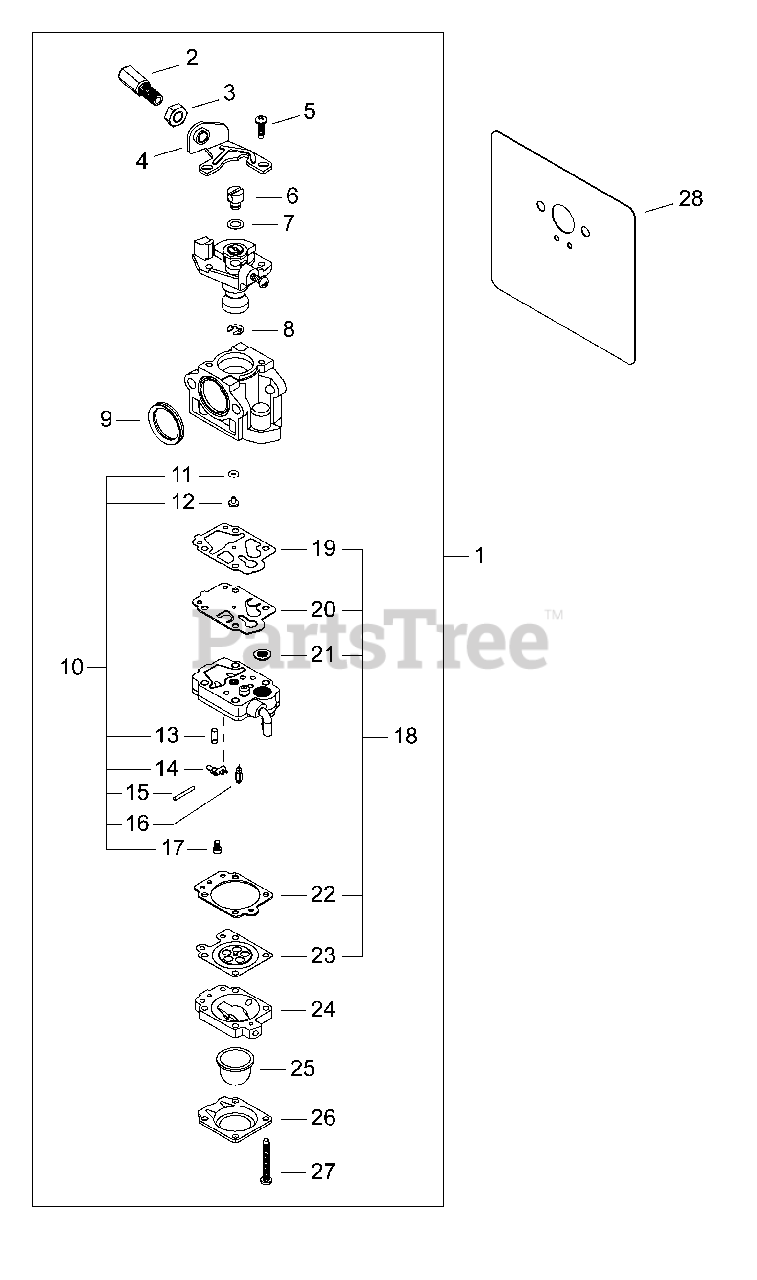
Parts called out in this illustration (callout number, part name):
1	CARBURETOR
2	ADJUSTER, THROTTLE CABLE
3	NUT, ADJUSTER LOCK M7
4	BRACKET, THROTTLE CABLE
5	SCREW
6	SWIVEL
7	WASHER
8	E-RING
9	RING, PACKING
10	VALVE KIT, INLET NEEDLE
11	O-RING
12	JET, MAIN
13	SPRING, METERING LEVER
14	LEVER, METERING
15	PIN, METERING LEVER
16	VALVE, INLET NEEDLE
17	SCREW
18	GASKET / DIAPHRAGM KIT
19	GASKET, PUMP
20	DIAPHRAGM, PUMP
21	SCREEN, FUEL INLET
22	GASKET, METERING DIAPHRAGM
23	DIAPHRAGM, METERING
24	BODY ASSY, PURGE
25	BULB, PURGE
26	RETAINER, PURGE BULB
27	SCREW
28	GASKET, INTAKE
